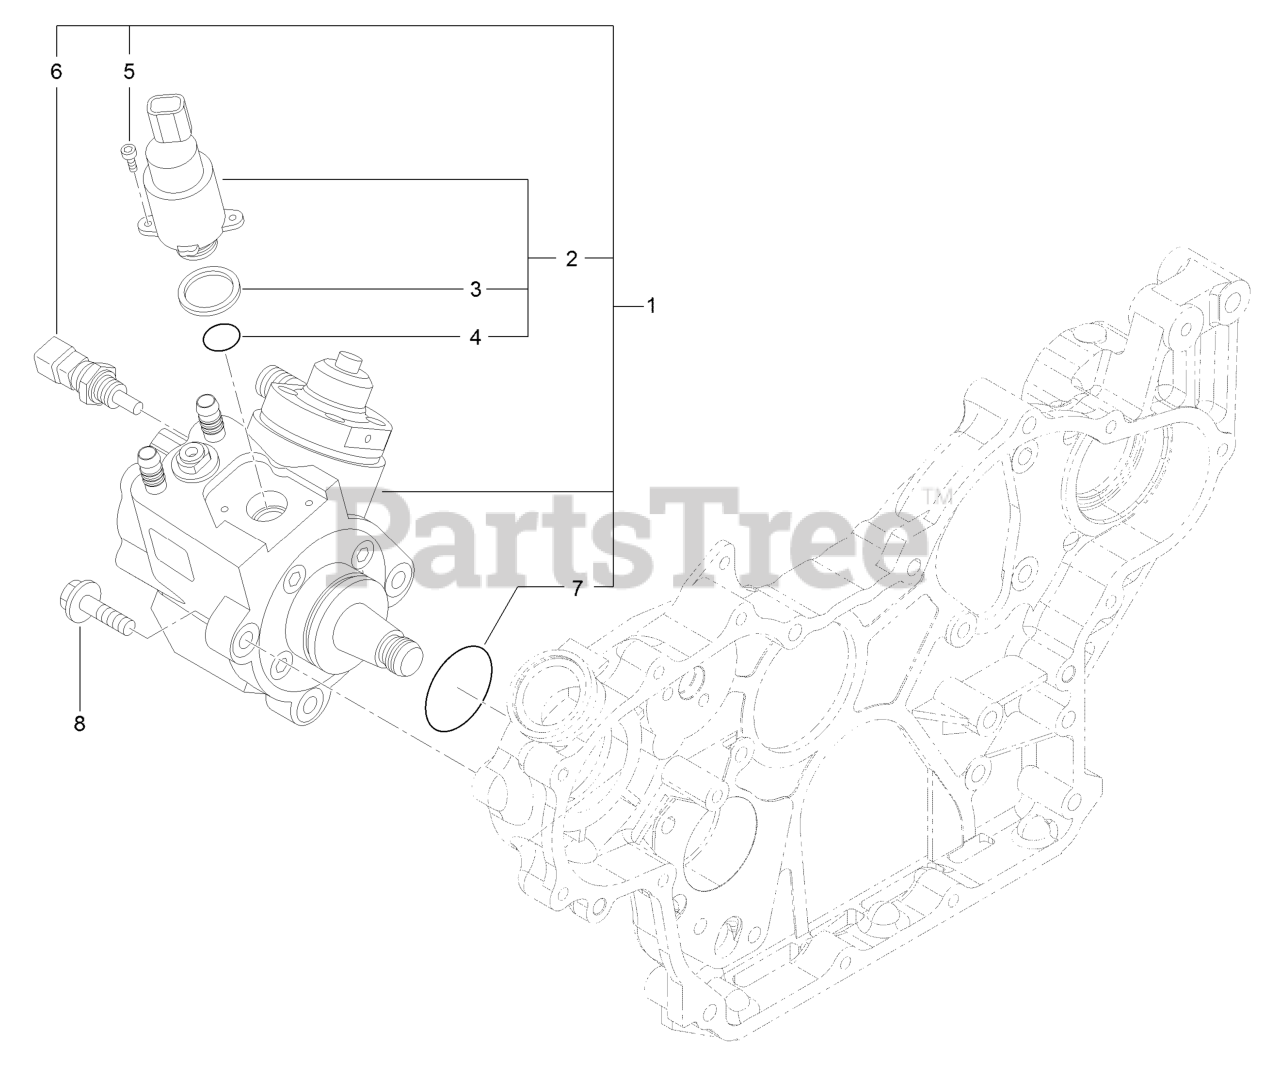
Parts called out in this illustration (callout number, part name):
1	Fuel Pump ASM
2	Valve ASM
3	Ring-Sealing
6	Sensor-Temperature
7	O Ring-Pump, Fuel
